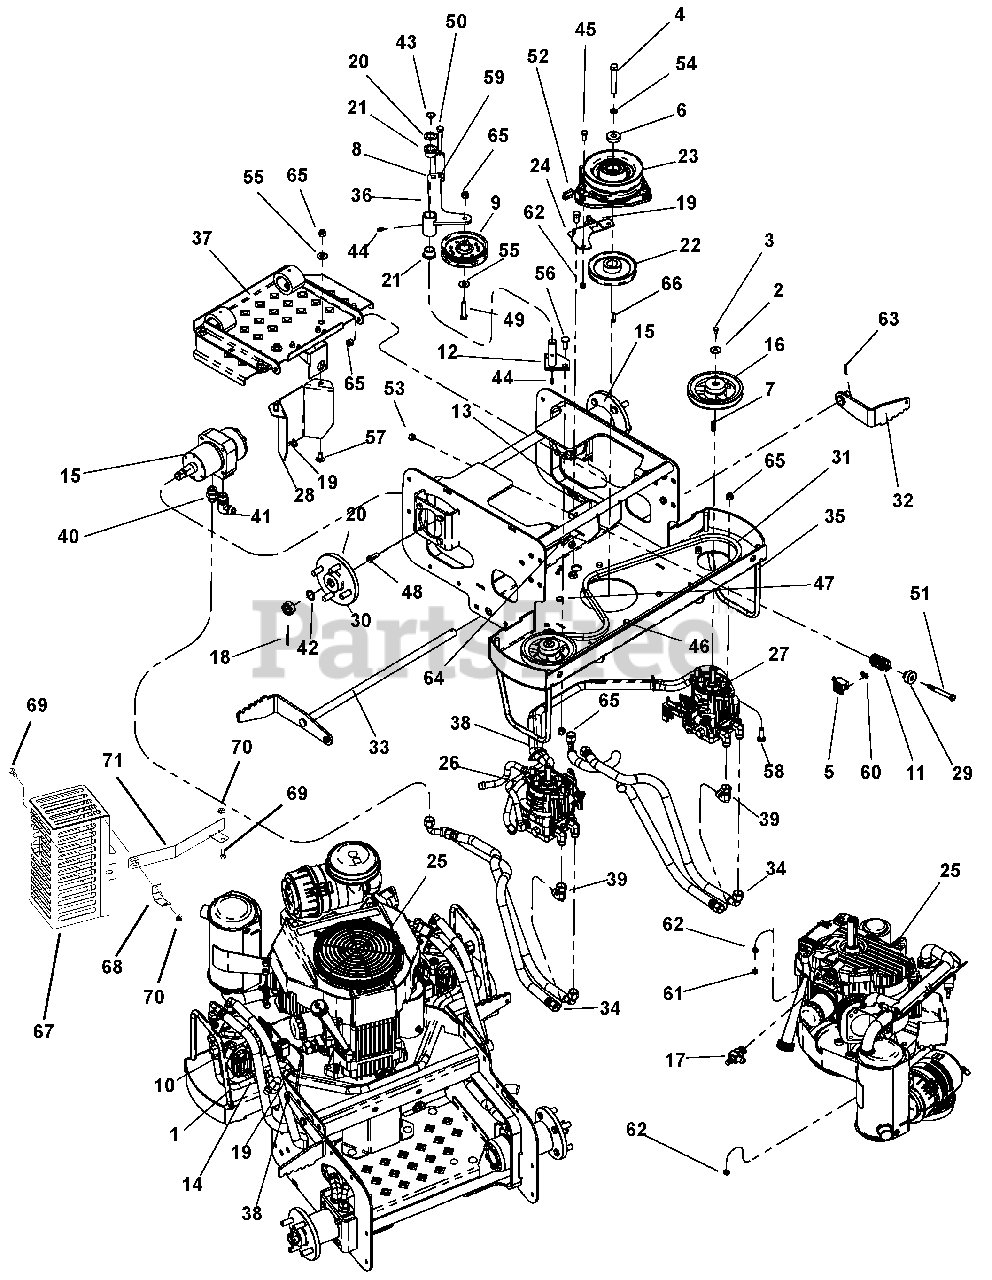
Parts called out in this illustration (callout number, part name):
1	HOSE, 3/8 SAE30R7 FUEL & OIL
2	WSHR-LK .250X.077 HVY YWZC
3	BOLT, M6X1.00X10 HEX 8.8 Y
4	BLT-HEX .44-20X3.00 GR5 YWZC
5	SWITCH (N.0.)
6	SPACER, PTO CLUTCH
7	KEY, SPECIAL M5 X 28
8	SPRING, IDLER
9	IDLER
10	HOSE CLAMP
11	SPRING
12	WLDT, PIVOT IDLER MOUNT
13	DECAL, WARNING-HOT SURFACE (RE
14	TEE FITTING
15	WHEEL MOTOR
16	PULLEY, RH PUMP SET SCREW INCL
17	OIL DRAIN FITTING
18	@PIN-CTR .125X2.00 YWZC
19	CABLE TIE, .15 X 8.50
20	WSHR-FL-STL .750X1.250X.048 YZ
21	BRG, FLG .750X1.00X.750 BRNZ
22	PULLEY, V-BELT 4.78PD X 1.000
23	CLUTCH ASSY, OGURA# GT1A-HU02
24	PLATE, CLUTCH DOG
25	ENGINE, KAWASAKI 19HP FH580V
26	ASSEMBLY, HYD PUMP
27	ASSEMBLY, HYD PUMP
28	COVER, OPC
29	WASHER, SPRING Y
30	ASSY, REAR WHEEL HUB
31	BELT, HA 68.2 EL AMD OHR
32	WLDT, RH BRAKE ARM
33	WLDT, LH BRAKE
34	HOSE, HYD 1/2 X 26 1/2 EZFLEX
35	L H INNER TINE SPOOL
36	WLDT, IDLER PIVOT
37	ASSY, FOOT PLATE
38	ABRASION SLEEVE
39	ADAPTER, 3/4 FESW X 3/4MJICX90
40	FTG, ADP 3/4-16MJICX7/8-14MOR
41	FTG, 7/8ORB X 3/4JIC X 90
42	SHIM, .020X.787X1.102
43	SNAP RING, .750 X .042 EXT
44	FTG, 1/4-28 STRGT GREASE ZERK
45	BOLT, 5/16-18X.750 HEX 5 Y
46	BOLT, 5/16-18X1.50 HEX 5 Y
47	BOLT, 5/16-18X1.75 HEX 5 Y
48	BOLT, 3/8-16X1.00 HEX 5 Y
49	BOLT, 3/8-16X1.75 HEX 5 Y
50	BOLT, 3/8-16X2.50 HEX 5 Y
51	BOLT, 3/8-16X3.25 HEX 5 Y
52	BOLT, 7/16-14X.750 HEX 5 Y
53	NUT, 3/8-16 STD HEX GR5 Y
54	WASHER, .375 MED SPRG LOCK Y
55	WASHER, .375 REG FLAT Y
56	BOLT, 3/8-16X1.00 CRG 5 Y
57	BOLT, 3/8-16X.750 CRG 5 LN Y
58	BOLT, 3/8-16X1.25 CRG 5 Y
59	NUT, 3/8-16 JAM GR5 Y
60	LOCKNUT, 10-24 NYLOC Y
61	NUT, 5/16-18 JAM GR5 Y
62	LOCKNUT, 5/16-18 NYLOC Y
63	PIN, ROL .156 X 1.00
64	SCREW, 10-24X.625 PAN PHL MACY
65	LOCKNUT, 3/8-16 NYLOC Y
66	KEY, .250 X .250 X .995 TPR
67	WMT-MUFFLER GUARD - PRO-STANCE
68	BRACKET, MUFFLER GUARD
69	@BLT-HEX .31-18X.75 GR5 YWZC
70	@NUT-LK-TOP-FLG .31-18 YWZC
71	SHIELD - MANIFOLD
